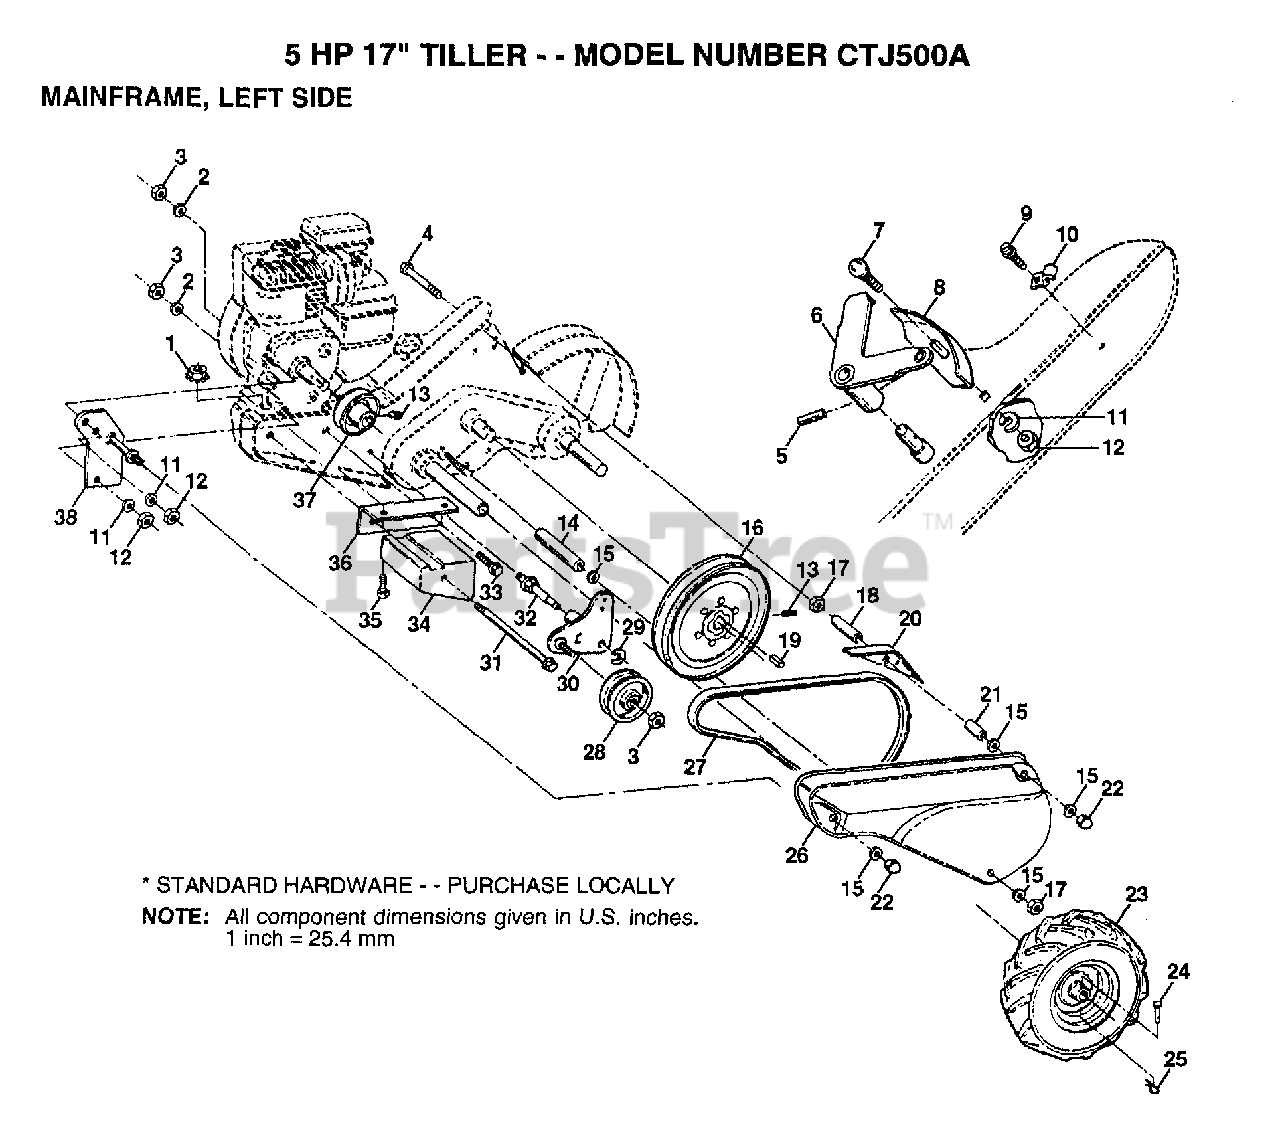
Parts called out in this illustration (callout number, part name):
2	LOCKWASHER
3	NUT.HEX.3/8-16UNC
4	BOLT TI
6	LEVER ASM CRT
7	BOLT
8	PANEL TI
10	CONDIUT CLIP T
11	LOCKWASHER
13	SET SCREW
14	SPACER
15	WASHER
16	"SHEAVE 10"" CRT"
17	NUT.HEX.5/16-18
18	SPACER CRT
19	KEY T
20	GUARD CRT
21	SPLIT SPACER
22	NUT TI
23	TIRE.CHV.13X5.0-6
24	RIVET.DRILL.1.75
25	RETAINER M
26	"GUARD, BELT"
27	BELT-V
28	PULLEY-IDLER TI
29	KLIP RING
31	BOLT CRT
32	SHIFT ARM CRT
33	BOLT
34	COUNTERWEIGHT CRT
35	BOLT.HEX.5/16-1.5
36	BRACKET LH CRT
37	ENGINE SHEAVE
38	BELT GUARD BRKT
